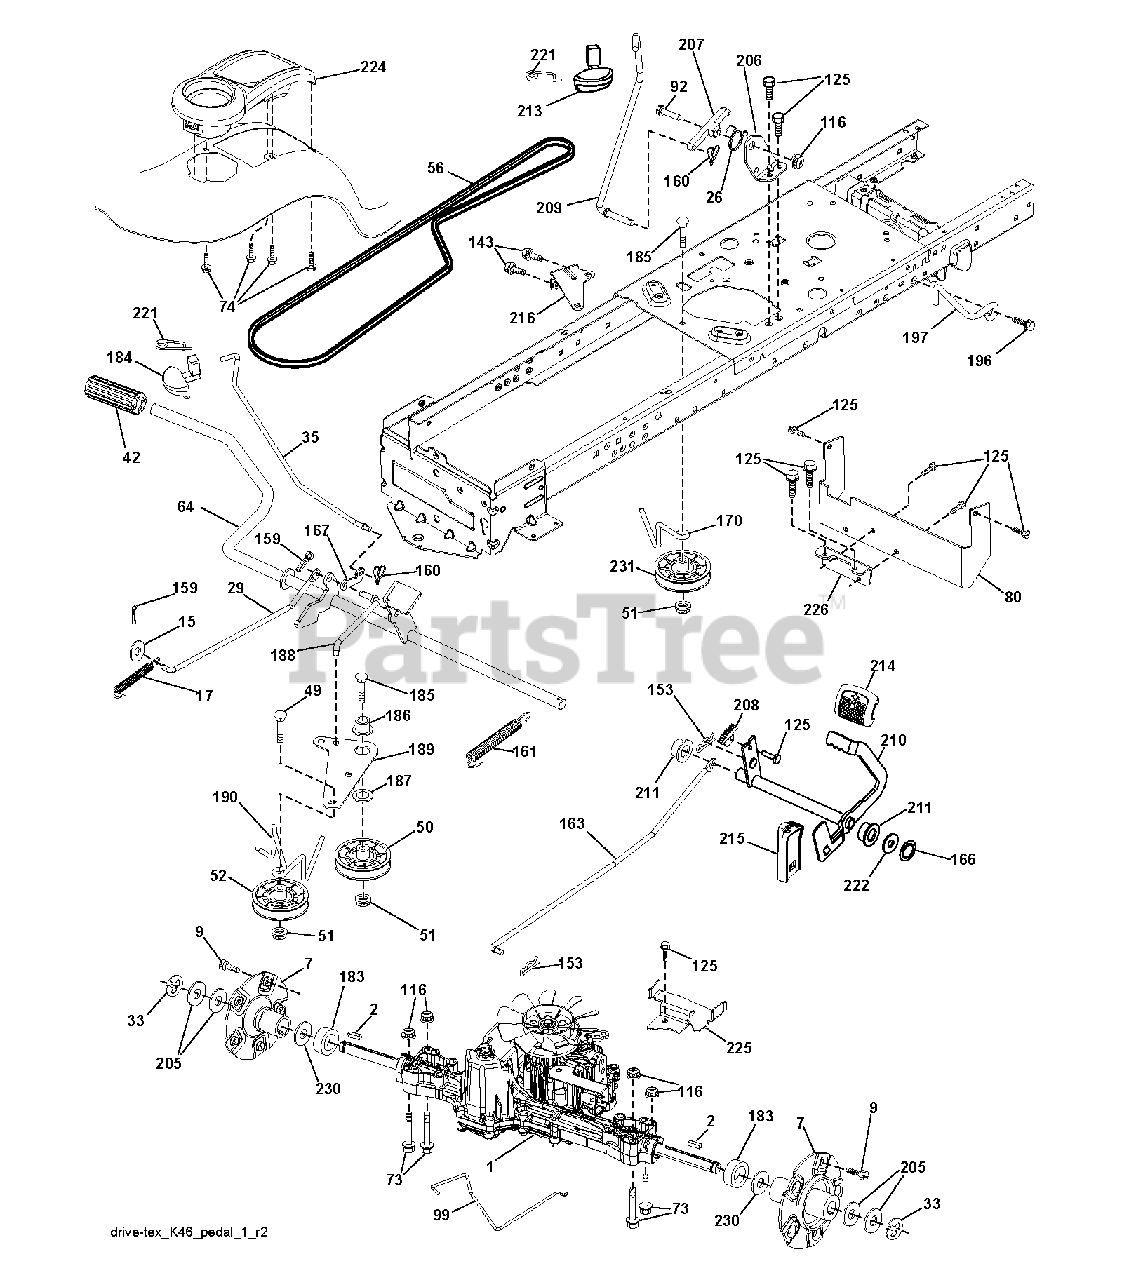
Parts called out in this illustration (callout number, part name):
2	KEY.SQUARE.187X2.500
7	HUB.ASM.WHEEL.REAR.22"
17	SPRING.BRAKE.K46.GREEN
26	SPRING.RETURN.CRUISE
29	ROD.BRAKE.K46
33	E-RING LT
35	ROD.BRAKE.PARKING.GT.H
42	PEDAL COVER T
49	BOLT
50	IDLER.FLAT.910.OFFSET
51	NUT LOCK FLG 3/8-16 UNC
52	IDLER.V-GROOVE.910.OFFSET
64	SHAFT.ASM.PEDAL.BRK.CNTR
73	BOLT HEX 5/16-18 GR 5
74	SCREW.HI-LO.CONSOLE
80	STRAP TORQUE
92	BOLT
99	ROD.SPRING.BYPASS.K46.LT.Z
116	NUT LOCK HEX FLANGE 5/16-18
125	SCREW
153	RETAINER M
159	COTTER PIN
160	RETAINER CLIP
161	SPRING, RETURN LT
163	ROD.CONTROL.PEDAL.K46
166	NUT.PUSH.625.2006
167	LATCH.BRAKE.SPRING
170	KEEPER.CENTER SPAN.1.688
183	SPACER.SPLIT.800X.350
184	HANDLE.PARKG.BRK.HUSQ/
186	SPACER.RETAINER
187	WASHER 12/32X2X10GA
188	LINK.CLUTCH.GROUND.DRIVE
189	BELLCRANK.GROUND.DRIVE.TEX.
190	KEEPER.BELLCRANK.DRIVE
196	SCREW 3/8-16X1
197	BRKT.ANIT-ROTATION.CLU
206	BRKT.MOUNT.LATCH.CRUIS
207	LATCH.CONTROL.CRUISE
208	GEAR.SECTOR.CONTROL.CR
209	ROD.CONTROL.CRUISE.GT.
210	ROCKER.ASM.PEDAL.CONTR
211	BEARING.NYLON
213	KNOB.CONTROL.CRUSIE.HU
214	PAD PEDAL FORWARD
215	PEDAL.REVERSE.TEX.GT.4
216	BRACKET.PULLEY.IDLER.W/TEX
221	RETAINER.SPRING.CLIP.H
222	WASHER 21/32 X 1-1/4 X 10 GA.
224	FEND/FTRST.PCH.CPH.NFW
225	KEEPER.BELT.TRANSAXLE.K46
226	BRACKET.MOUNT.TORQUE.K46.TLT
230	WASHER.HARDENED
231	IDLER.V-GROOVE.1.688.OFFSET
